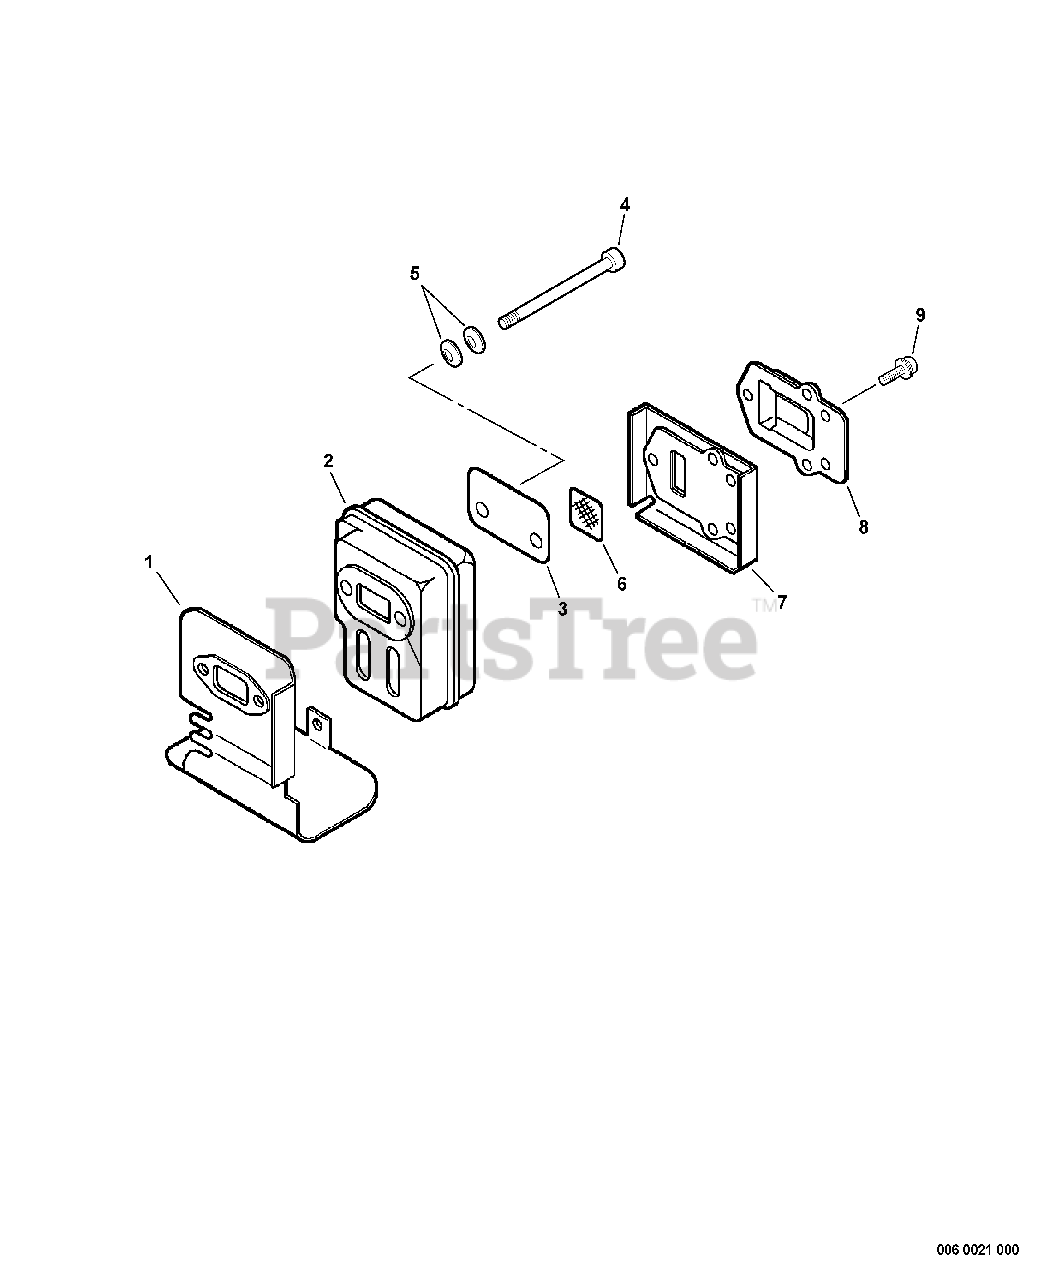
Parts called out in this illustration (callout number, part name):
1	HEAT SHIELD, EXHAUST
2	MUFFLER
3	PLATE, EYE
4	BOLT 5×55
5	CONICAL WASHER
6	SCREEN, SPARK ARRESTER
7	GASKET, EXHAUST
8	GUIDE, EXHAUST
9	SCREW 4×12
